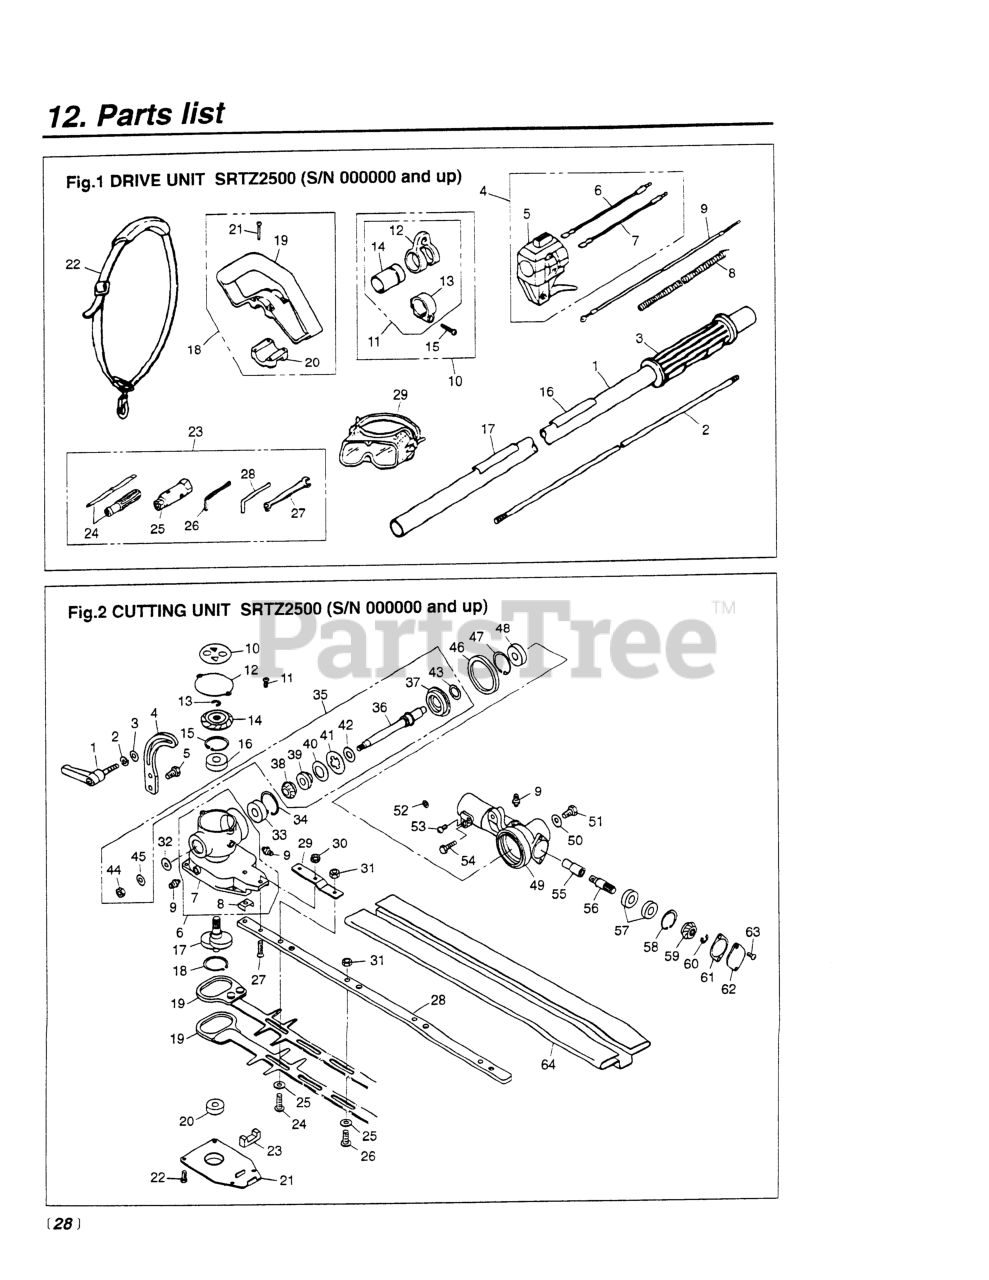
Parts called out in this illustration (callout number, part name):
1-1	PIPE COMPLETE
1-2	SHAFT
1-3	GRIP (RPLS 3577-32140 & 3220-
1-6	CORD (A), BLACK
1-7	CORD (B), RED
1-8	TUBE (RPLS 4900-72141)
1-9	CABLE (RPLS 5580-83100)
1-10	HANGER ASSEMBLY
1-11	HANGER COMPLETE
1-12	HANGER
1-13	CLAMP
1-14	SLEEVE
1-15	SCREW, M5 x 25
1-16	LABEL (SRTZ2500)
1-17	LABEL (CAUTION)
1-18	HANDLE ASSEMBLY
1-19	HANDLE
1-21	SCREW, M5 x 35
1-24	SCREWDRIVER
1-25	SOCKET
1-26	WRENCH (TOOL)
1-27	SPANNER, 8 X 10 (RPLS 2540- )
1-28	BAR
1-29	GOGGLE
2-2	WASHER, M6 X 15
2-4	ADJUSTER, ANGLE (USE-13141)
2-6	CASING (RPLS -13210)
2-7	CASING A
2-8	PLATE
2-9	FITTING, GREASE
2-10	LABEL
2-11	SCREW, M4 X 8
2-13	RING, SNAP
2-14	GEAR, BEVEL
2-15	RING, SNAP, M26 X 1.2
2-16	BEARING
2-17	CRANKSHAFT
2-18	RING, SNAP, M28 X 1.5
2-19	BLADE, SRT, 24
2-20	BEARING
2-23	FELT
2-25	WASHER (RPLS 3873-11760)
2-26	SCREW
2-27	SCREW, M5 X 20
2-28	PLATE, GUIDE
2-29	PLATE (RPLS 6780- )
2-30	NUT, M5
2-31	NUT, M6
2-32	WASHER, 6X15X2.0
2-33	BEARING
2-34	RING, SNAP, M22 x 1.2
2-35	KIT, SHAFT (RPLS 6782-13610)
2-36	SHAFT
2-37	GEAR (B)
2-38	GEAR (C)
2-39	BOSS
2-40	WASHER, SPRING
2-41	PLATE
2-42	WASHER
2-43	WASHER
2-44	NUT, M6 X 5
2-45	WASHER, M6 X 15
2-46	O-RING
2-47	RING, SNAP, M26 X 1.2
2-48	BEARING
2-49	CASE- B
2-50	RING, SNAP
2-52	WASHER
2-53	BOLT, M5 X 10
2-54	BOLT
2-55	JOINT (USE 6782-13810)
2-56	SHAFT, GEAR
2-57	BEARING
2-58	RING, SNAP, M22 x 1.2
2-59	GEAR, BEVEL
2-60	RING, SNAP
2-61	PACKING
2-62	COVER, STOPPER KIT
2-63	SCREW, M4 X 8
2-64	COVER, BLADE
